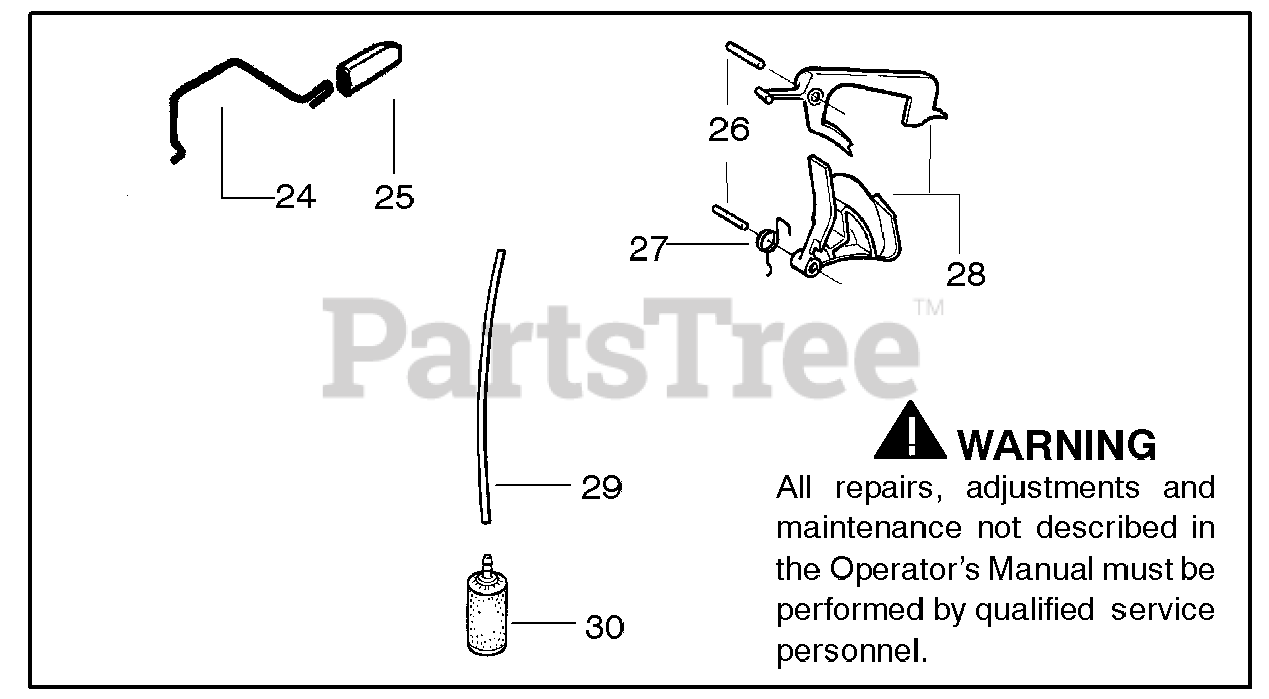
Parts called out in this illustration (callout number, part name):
24	THROTTLE SHAFT 36/41
25	THROTTLE ACTUATOR 36/41
26	PIN,TRIGGER 36/41
27	TRIGGER SPRING 36/41
28	THROTTLE TRIGGER-KIT
29	HOSE. FUEL
30	FUEL PICK-UP
